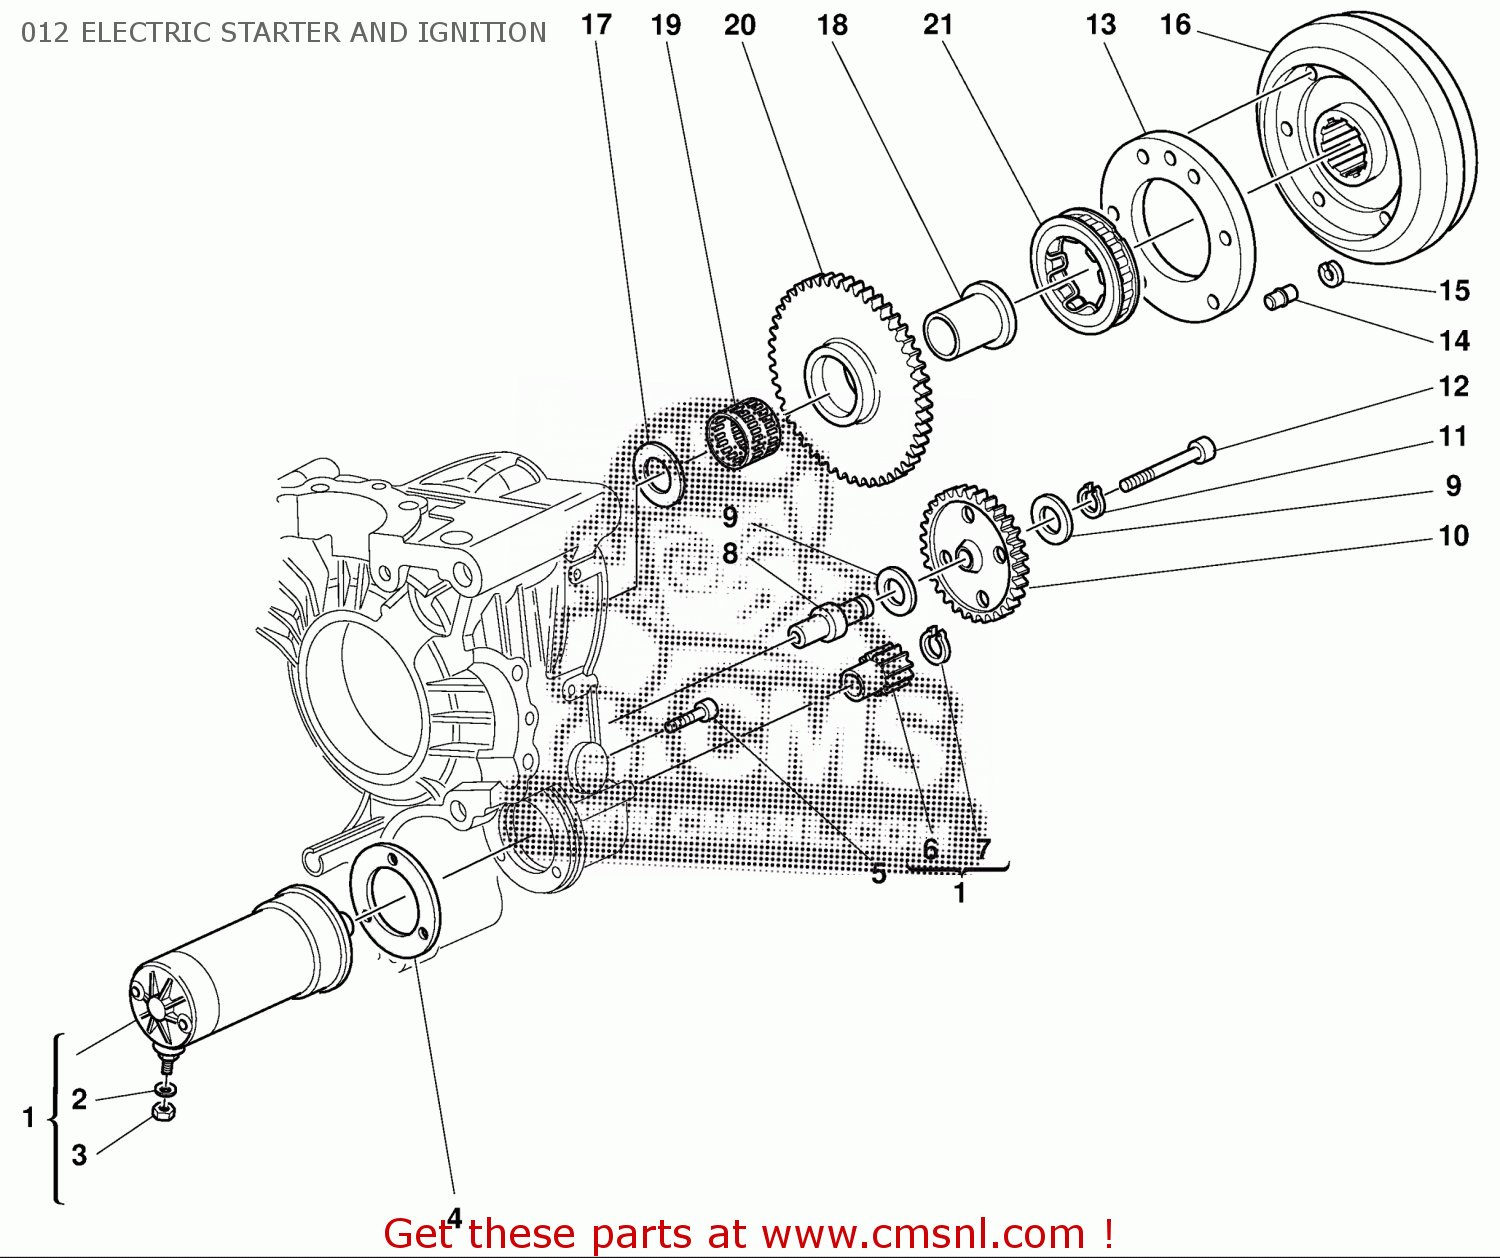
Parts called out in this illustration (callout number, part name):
1	STARTING MOTOR
2	WASHER, SPRING
3	NUT
4	ENGINE STARTER GASKET
5	BOLT, SOCKET HEAD M6X25
6	PINION STARTER MOTOR
7	CIRCLIP
8	STARTER REDUCTION SHAFT
9	WASHER
10	IDLE GEAR
11	CIRCLIP 14 DIN 471
12	SCREW M6X65
13	FLANGE STARTING CLUTCH
14	PIN DOWEL
15	STOP RING
16	FLYWHEEL
17	THRUST WASHER 35.5X48
18	BUSH
19	BEARING, NEEDLE
20	GEAR, ELECTRIC STARTER T71
21	CLUTCH, ONE WAY
